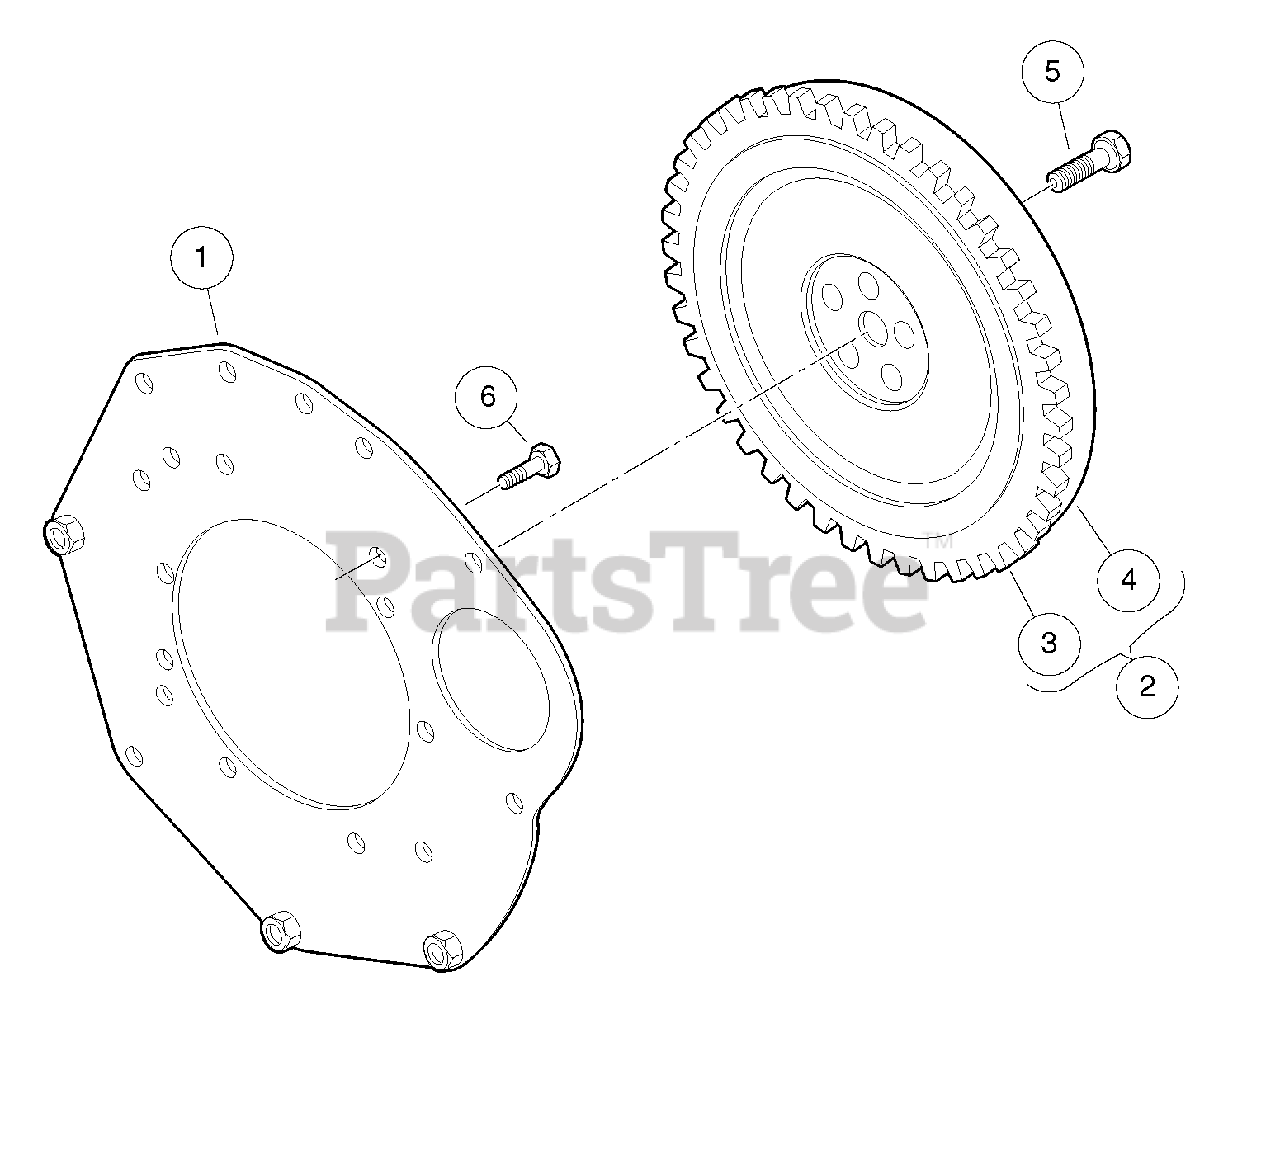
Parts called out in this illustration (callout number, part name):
1	Plate, Rear End
2	Flywheel
3	Gear, Ring, D722
4	Flywheel
5	Bolt, Flange Head, M10 X 1.5 X 25
6	Bolt, End Plate
